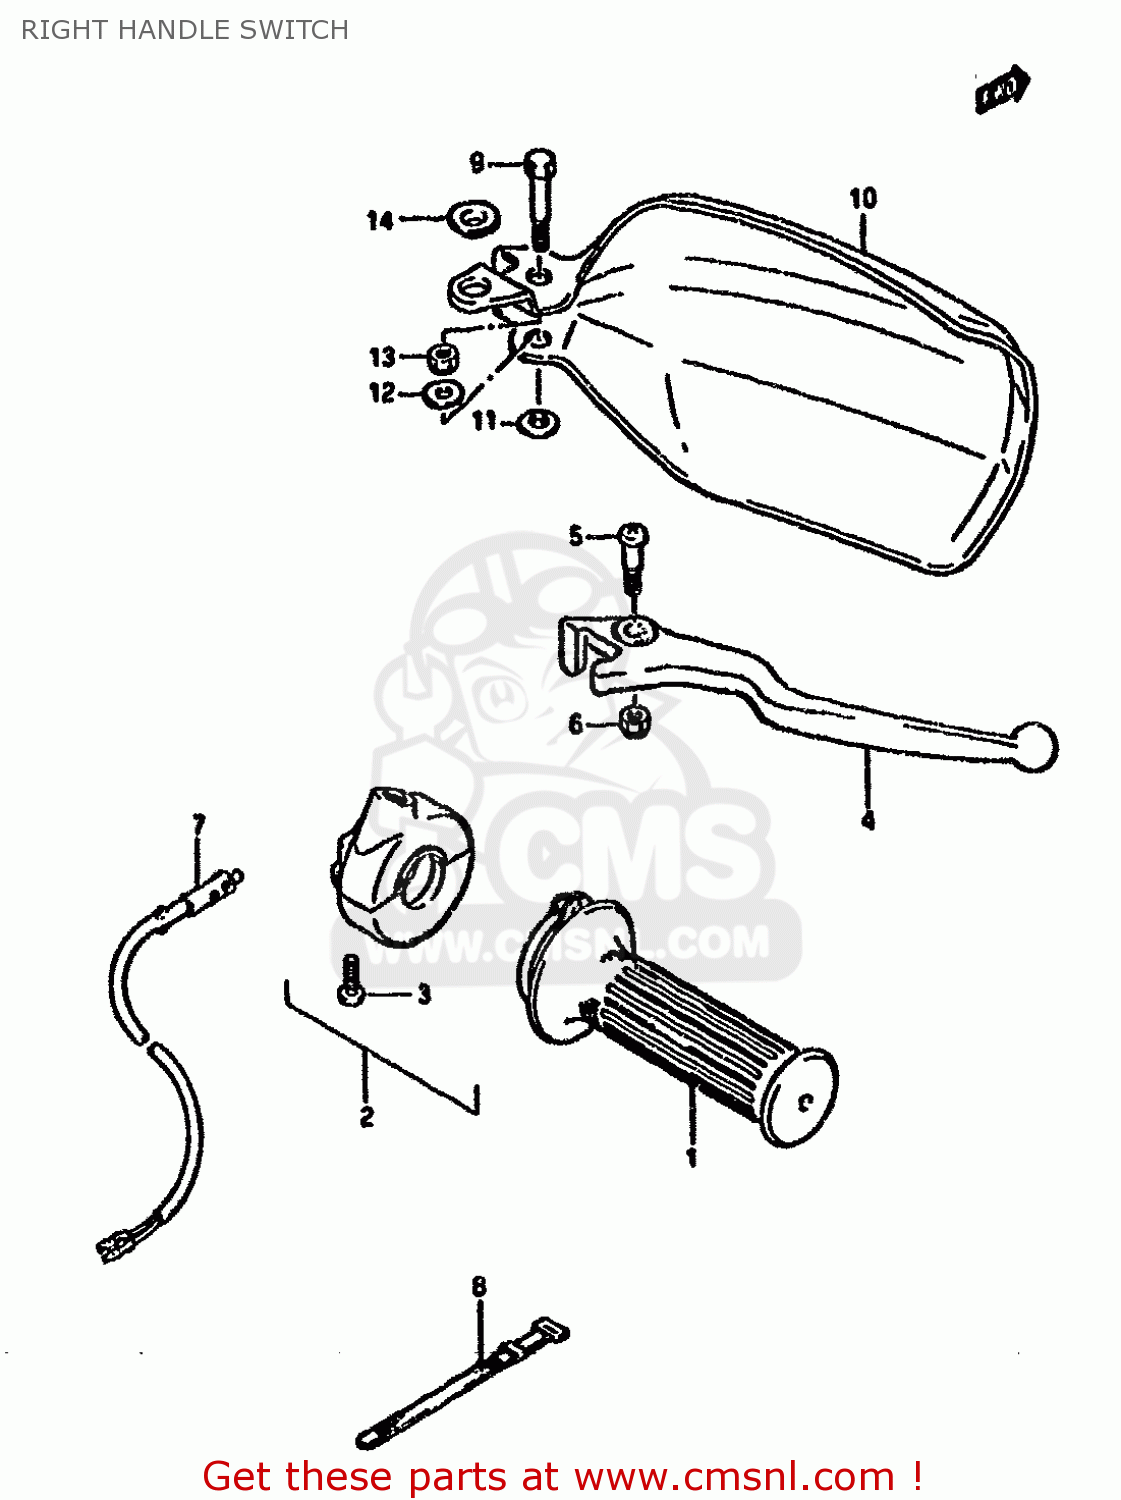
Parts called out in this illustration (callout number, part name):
1	GRIP,THROTTLE
2	CASE ASSY,THROTTLE
3	SCREW 5X20
4	LEVER,BRAKE
5	SCREW
6	NUT
7	SWITCH ASSY,STOP
8	CLAMP(L:120)
9	BOLT,LEVER PIVOT
10	COVER,KNUCKLE,R
11	WASHER
12	WASHER(6.5X16X1.2)
13	NUT 6MM
14	WASHER
